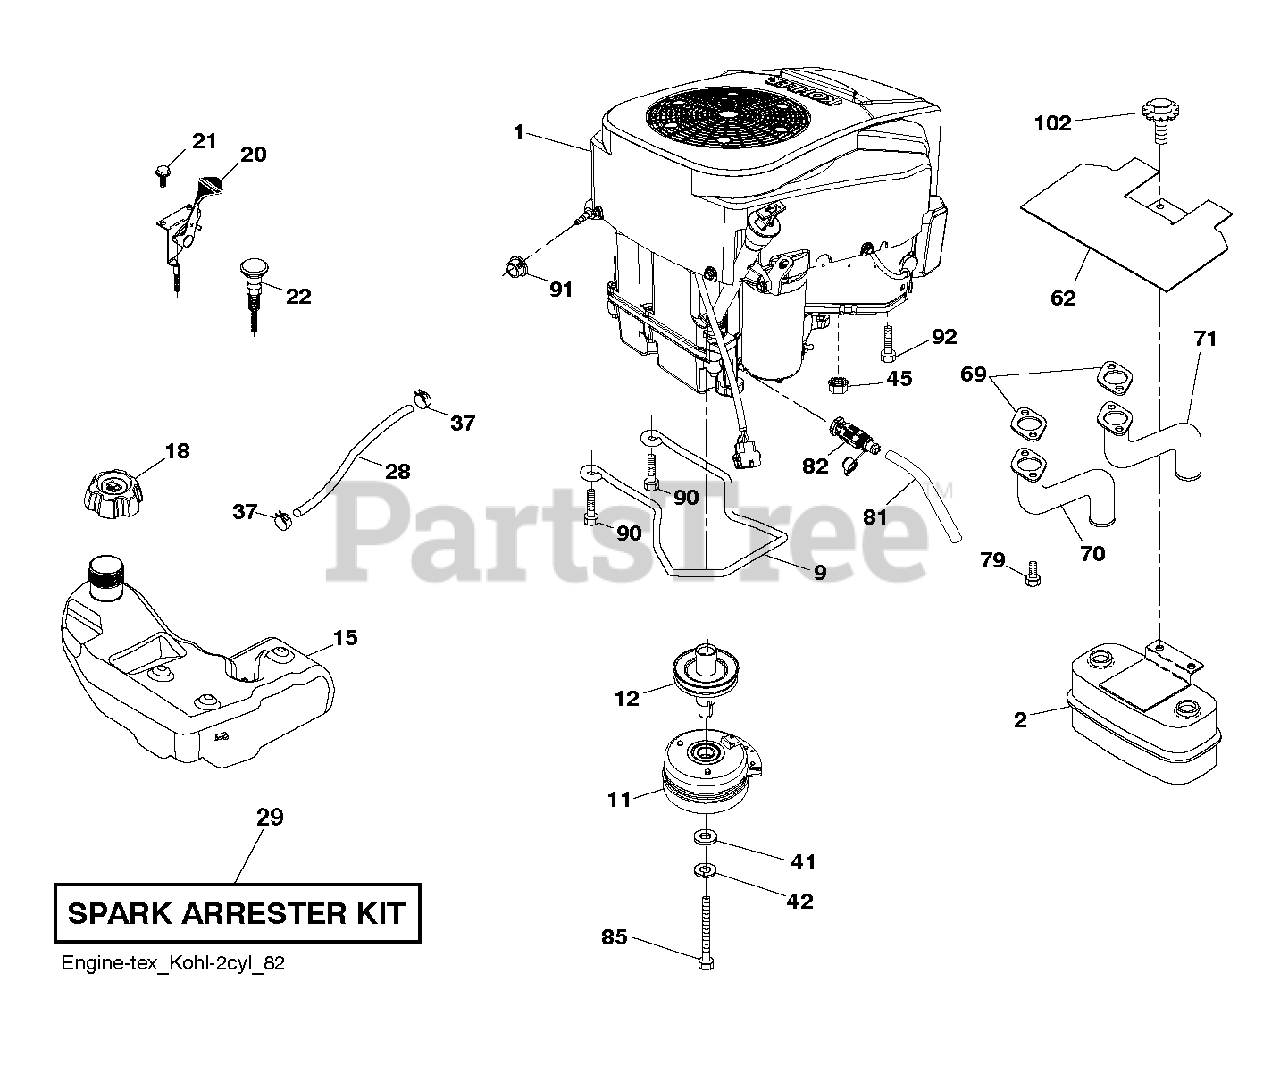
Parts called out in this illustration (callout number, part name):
2	Muffler Assembly, Twin MN
9	KEEPER.BELT.ENG.4.25"2.BLT.431
11	CLUTCH. 5.0 PD. 2.5 OFFSET
12	PULLEY.EXTENDED.SHAFT.GROUND
15	Tank Assembly 3Gal.Epa.18
18	CAP ASSY FUEL 3" GRAY
20	THROTTLE CONTROL
21	SCREW.#10 X 0.750.BOS
22	CONTROL.CHOKE.ERGO.PUSH-IN.BLA
28	HOSE.1/4".LOW.PERM.FUEL.LN.60"
29	KIT.SPARK ARRESTOR 794945 B&S
37	HOSE CLAMP
42	WASHER 7/16 LOCK
45	NUT
62	SHIELD.HEAT.MUFFLER
69	GASKET.EXHAUST.KOHL.CV18-CV26
70	PIPE.EXHAUST.LH.CV18/20
71	PIPE.EXHAUST.RH.CV18/20
79	SCREW.SOCKET HD.5/16-1
81	TUBE, DRAIN OIL ASM.
82	VALUE.OIL.DRAIN
85	BOLT.HEX.7/16-20X5.GR5.GREEN
90	SCREW 3/8-16X1
91	BUSHING.1.375OD
92	SCREW 3/8-16X1
102	SCREW
